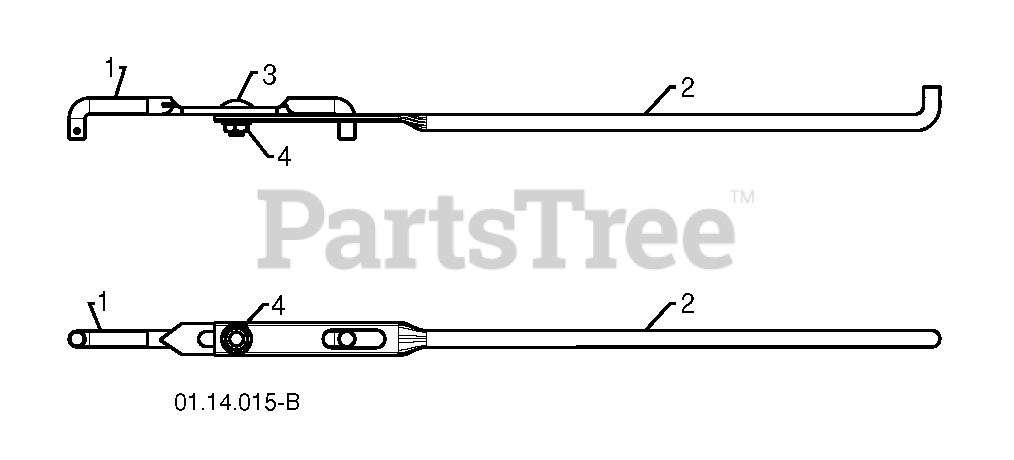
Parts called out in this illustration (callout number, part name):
1	ROD.SHIFTER.TOP.HYD
2	ROD, LOWER, SPEED CONTROL
3	BOLT
4	NUT.FLANGE.5/16
